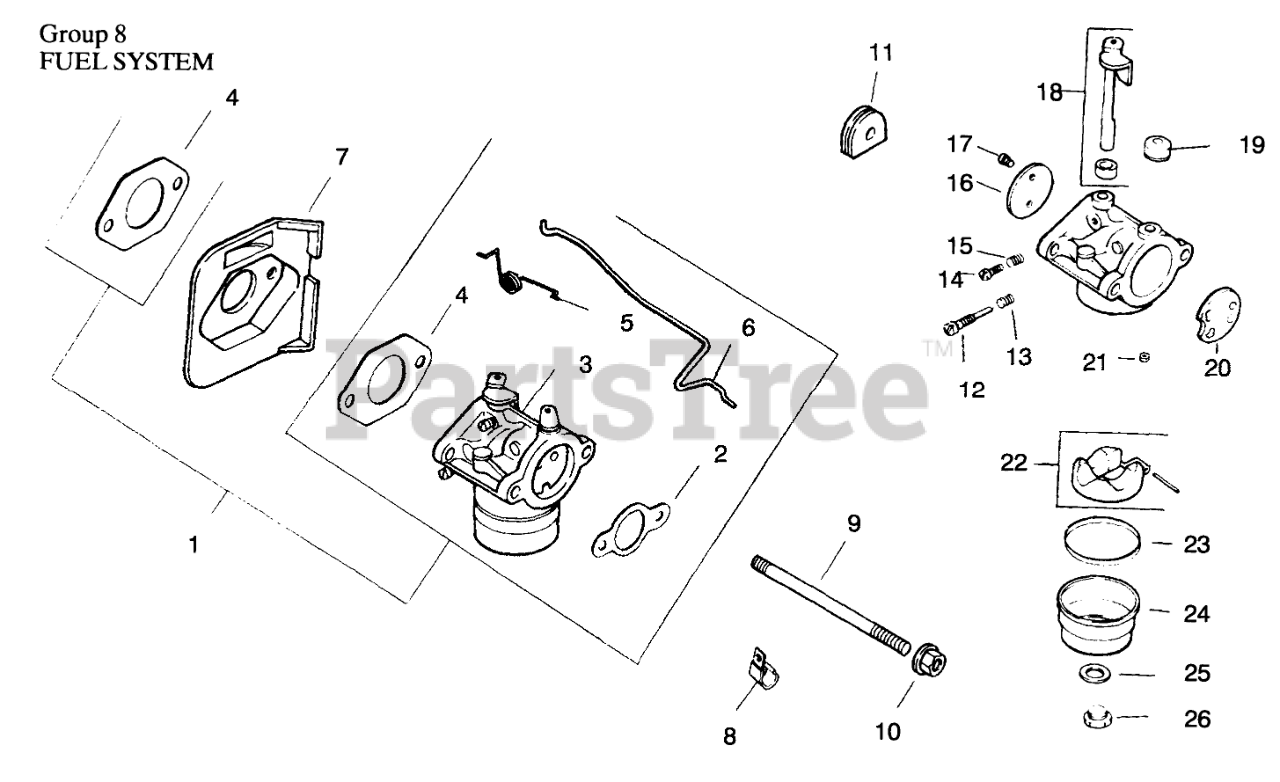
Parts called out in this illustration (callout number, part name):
1	Kit-Carburetor (Incl Ref. #2-6)
2	Gasket-Air Cleaner
3	Carburetor Assembly (Incl Ref. #12-26)
4	Gasket-Carburetor
5	Spring Choke
6	Linkage Choke
7	Deflector-Heat
8	Clamp
9	Stud
11	Grommet
12	Needle-Idle
13	Spring-Idle
14	Screw-Idle
15	Spring-Idle
16	Plate-Choke
17	Screw
18	Shaft-w/Lever & Seal
19	Cap-Choke Lever
20	Plate-Choke
21	Jet-Main
22	Kit-Float
23	Gasket-Bowl
24	Bowl-Fuel
25	Gasket-Bowl
26	Screw-Bowl
